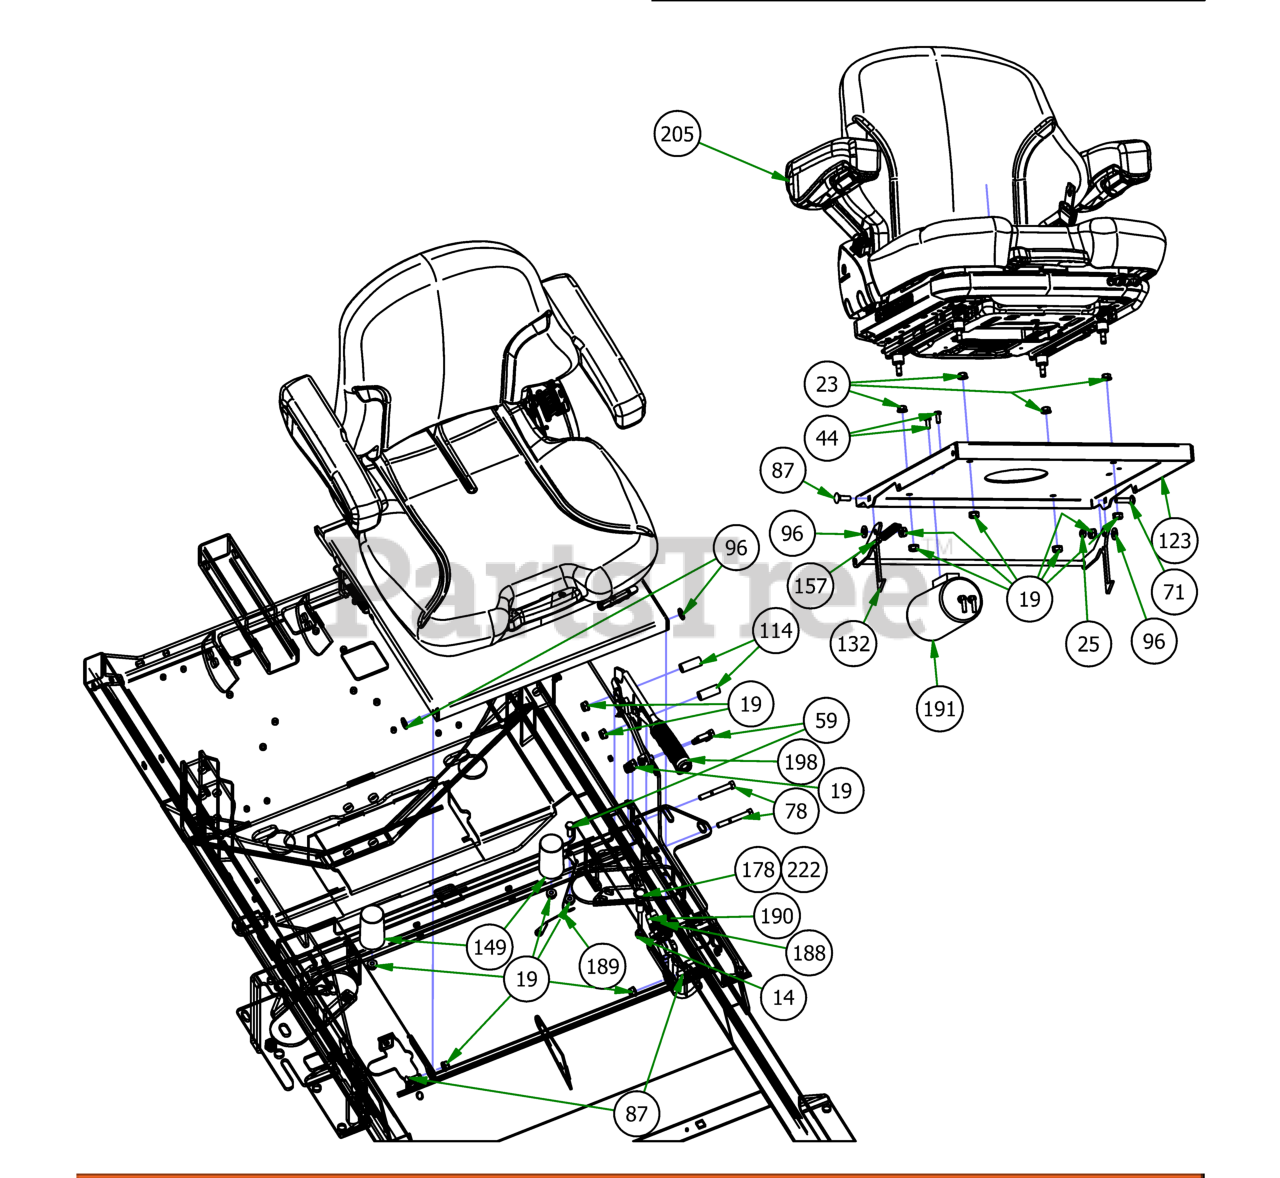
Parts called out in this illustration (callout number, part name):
14	3/8" Fine Threaded Jam Nut
19	5/16-18 Nylon Flange Nut
23	5/16" Flange Nut
25	5/16-18 Nylock Jam Nut 1/2 Nut
44	M6-1.0 X 16MM Hex Bolt
59	5/16" x 1" Bolt
71	5/16" x 1 1/4" Carriage Bolt
78	5/16" x 2 1/2" Bolt
87	5/16" x 1" Carriage Bolt
96	.360 ID Plastic Washer
114	2019 Outlaw Brake Handle Spacer .625 x 1.5
123	2019 Outlaw Seat Plate
132	Seat Latch Rod Assembly
149	2019 Bad Boy X Cylindrical Seat Mount
157	Brake Spring
178	Choke for 36Hp Vanguard & FX1000 Kawasaki
188	2019 Short Brake Cable-Suspension Models
189	Seat Cable
190	2019 Long Brake Cable-Renegade, Rogue
191	2019 Outlaw EPA Cannister Assembly
198	2019 Brake Handle Assembly
204	2019 Renegade Gas Frame - Powdercoated
205	2019 Renegade Seat
222	Code Indicator Light
